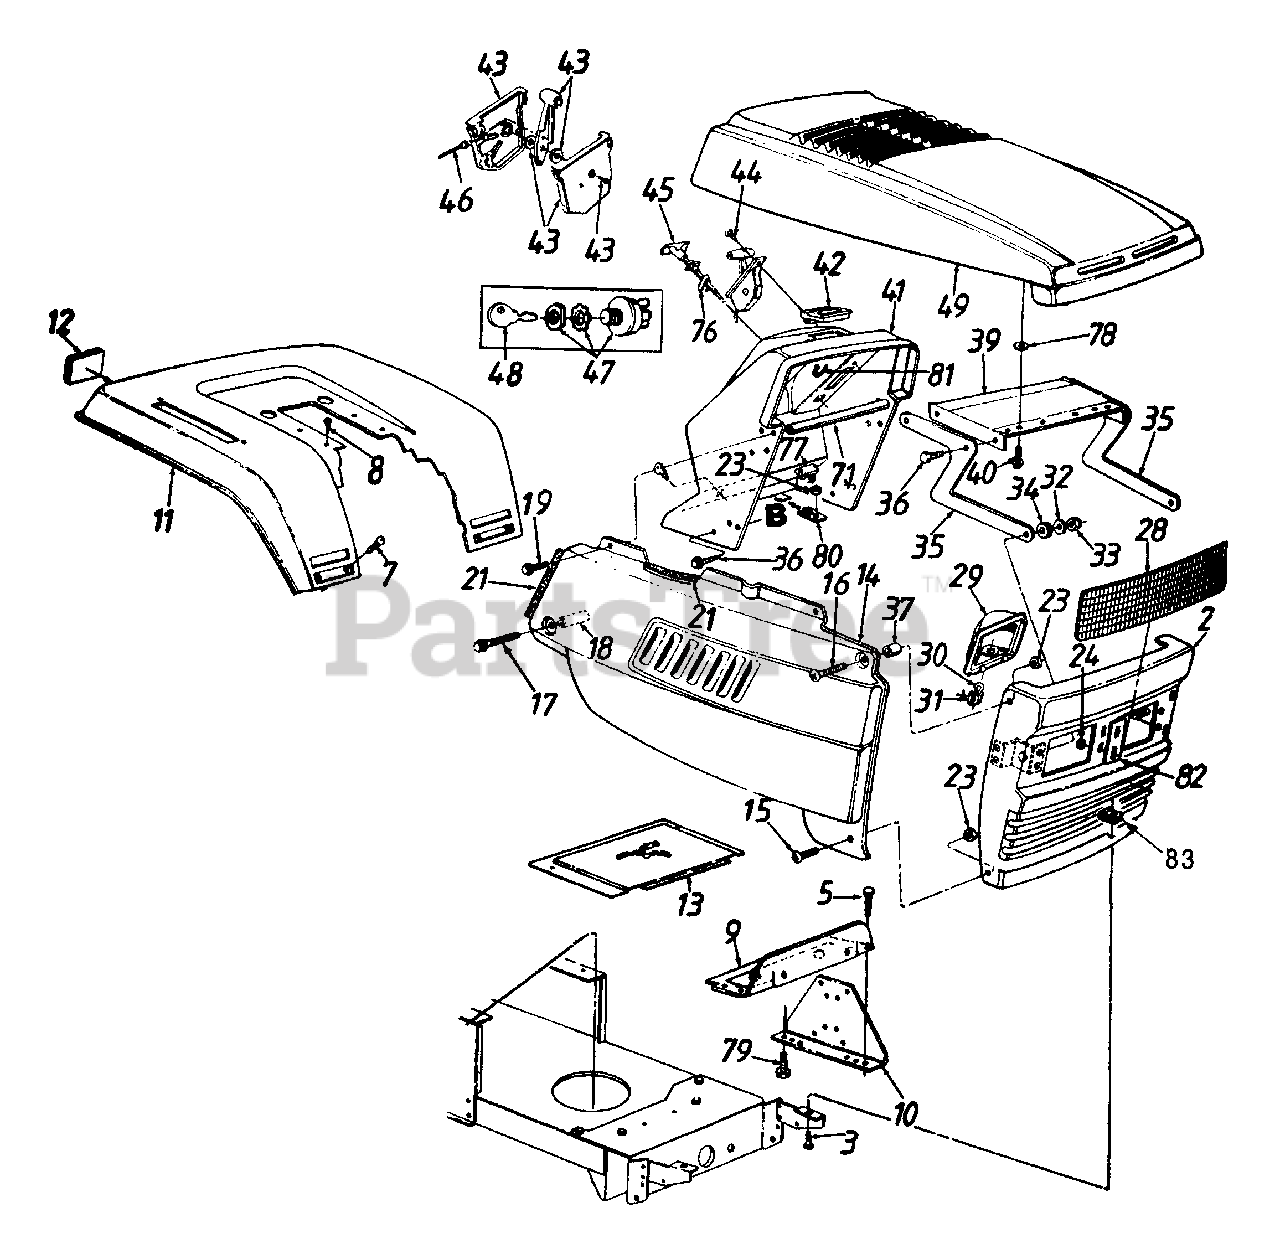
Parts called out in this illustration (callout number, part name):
3	Hex Bolt 5/16-18 x .75" Lg.
5	Hex Wash. Hd. Scr. 5/16" x .5" Lg.
7	Truss Mach. Scr. 1/4-20 x .5" Lg.
8	Hex Wash. Hd. Tap Scr. 5/16 x .75" Lg.
16	Truss Mach. Scr. 1/4-20 x 1.0"
17	Hex Wash. TT-Tap Scr. 1/4-20 x
18	Spacer .26" I.D. x 1.32"
19	Hex Rolling Tap Scr. 1/4-20 x .75" Lg.
21	Trim Strip 18" Lg.
23	Hex Sems Nut 1/4-20 Thd.
24	Speed Nut 5/16" Thd.
29	Headlamp Housing
30	Headlamp
31	Twist Lock Lamp Socket
32	Bell-Wash. .345" I.D. x .88"
33	Hex L-Nut 5/16-18 Thd.
34	Rubber Washer
37	Spacer .262" I.D. x .31"
41	Dash
42	Ammeter
43	Throttle Control Box Ass'y.
44	Mach. Scr. #10 x .44" Lg.
45	Choke Control 23" Lg.
46	Throttle Control Wire 18.5" Lg.
47	Ignition Switch
48	Ignition Key
49	Hood - Red
71	Grille Support Tube
76	Choke Retainer
77	Light Switch
78	Fl-Wash. .406" I.D. x .812" O.D.
79	Hex Bolt 1/4-20 x .88" Lg.
80	Dash Fastening Tab
81	Cable Tie
82	Chrome Label
83	U-Nut 5/16-18 Thd.
